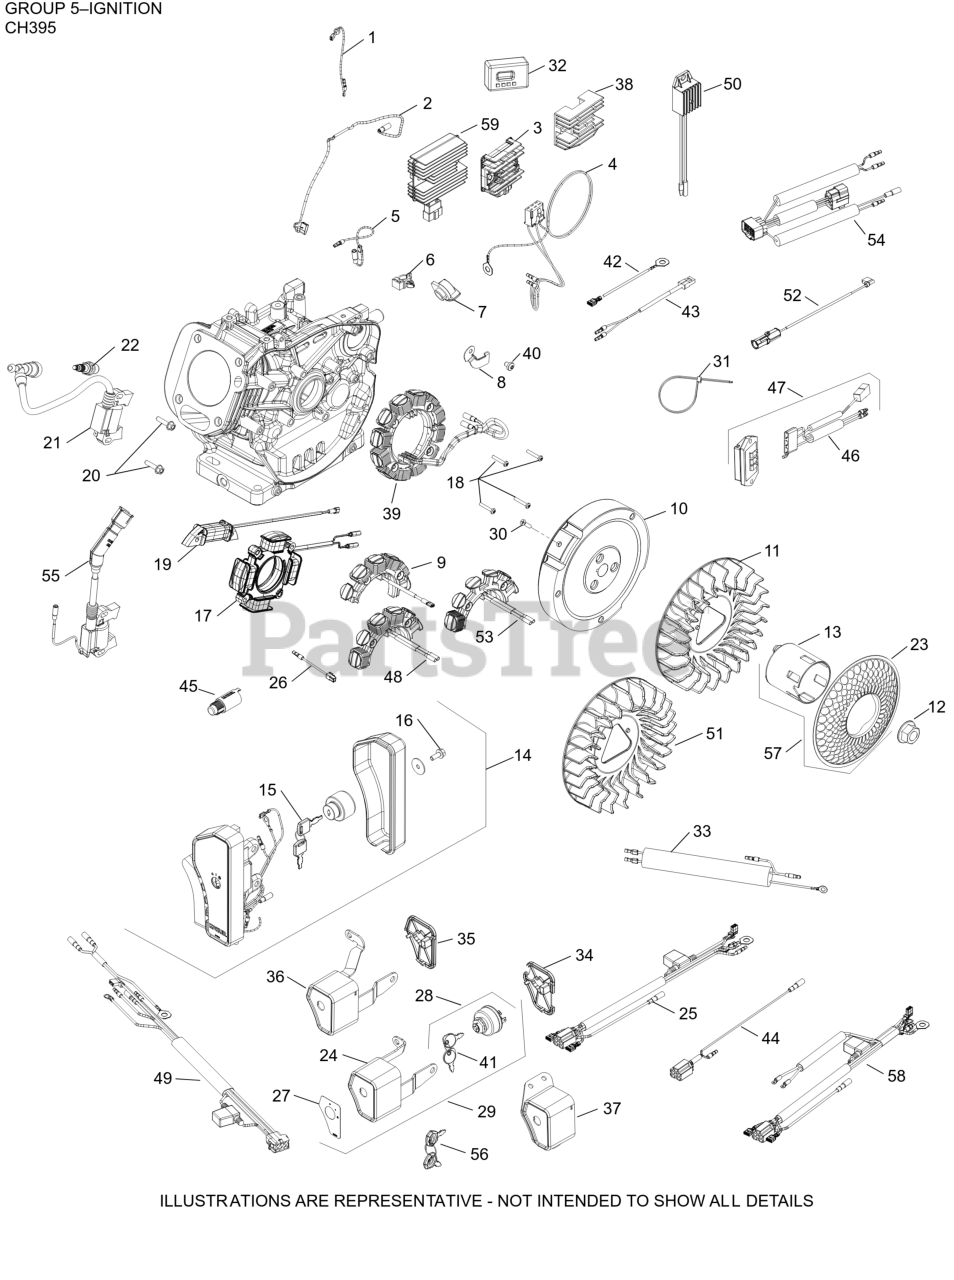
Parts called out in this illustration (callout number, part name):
2	LEAD, GROUND TO KILL
6	CLIP, WIRE HARNESS
10	FLYWHEEL ASSY,CAST IRON (RECOIL)
11	FAN, FLYWHEEL
12	NUT, FLYWHEEL
13	CUP, STARTER DRIVE
20	SCREW, M6 X 25-(#25086436S)
21	MODULE, SPARK PLUG ASSY
22	SPARK PLUG
33	LEAD, MICROSWITCH
